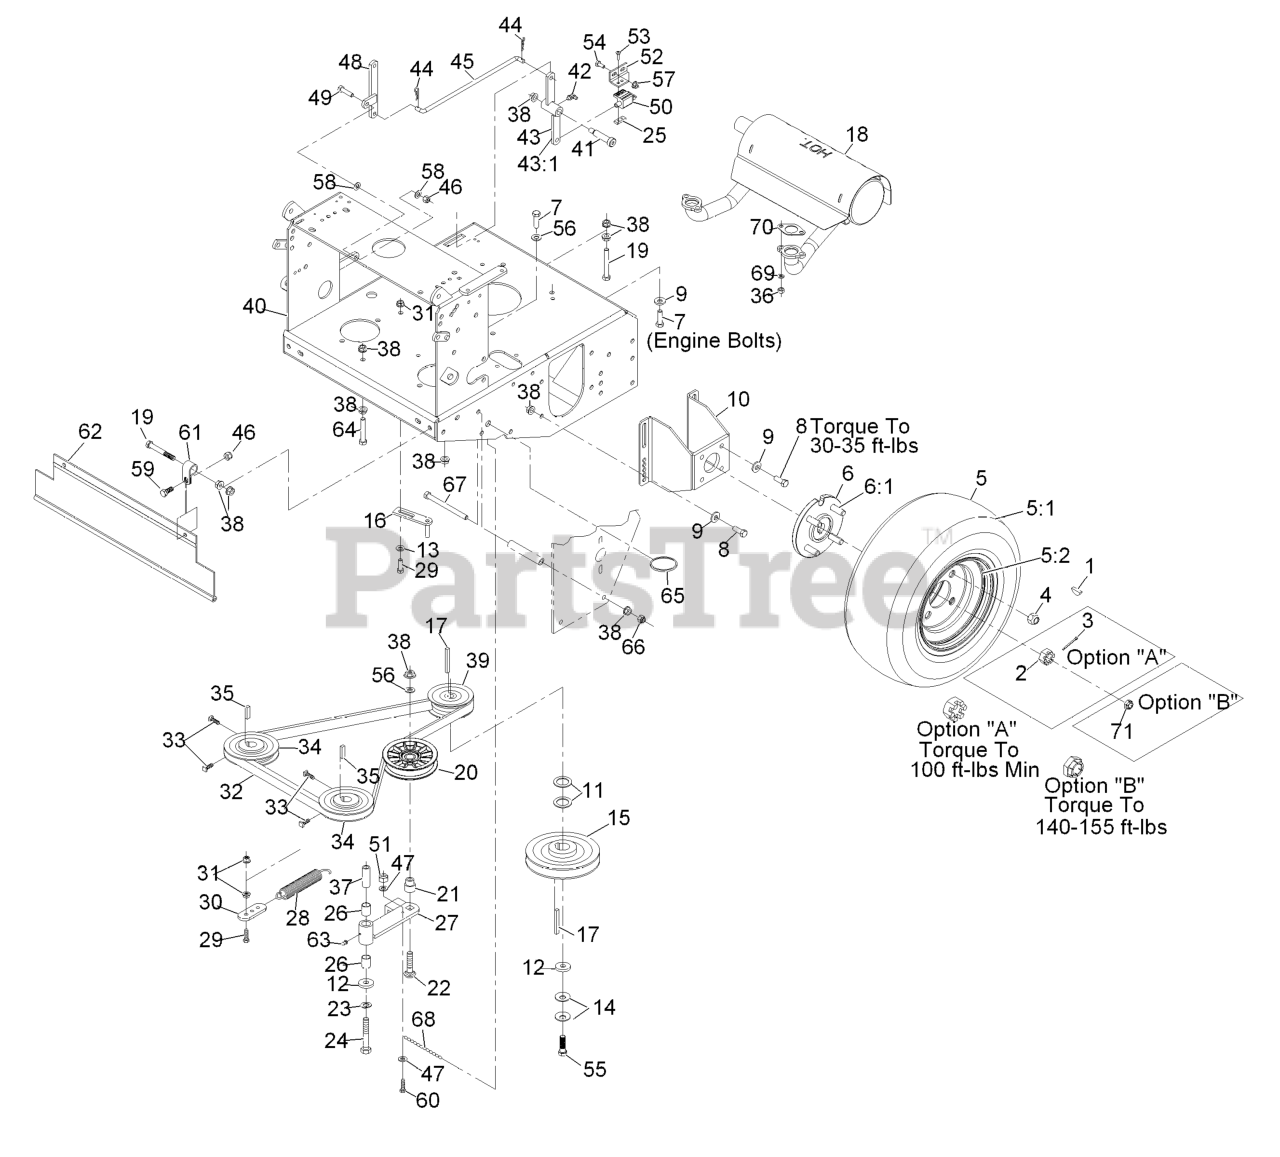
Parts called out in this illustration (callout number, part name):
1	KEY-WOODRUFF
2	NUT-HEX, SLOTTED
3	PIN-COTTER
4	NUT-LUG
5	WHEEL AND TIRE ASM
5:1	TIRE-TURFMASTER
5:2	RIM-WHEEL
6	WHEEL HUB ASM
6:1	STUD-WHEEL
7	SCREW-HH
8	SCREW-HH
9	WASHER-BELLEVILLE
10	MOUNT-MOTOR
11	WASHER-SPACER
13	WASHER-SPRING
14	WASHER-SPRING
16	GUIDE-BELT
18	MUFFLER,HORIZONTAL
19	SCREW-HH
20	PULLEY-IDLER, FLAT
21	BUSHING-IDLER
22	SCREW-CARR
23	WASHER-LOCK
24	BOLT-CARR
25	PLATE-TAPPED
26	SLEEVE-BEARING
27	IDLER ARM ASM
28	SPRING-EXTENSION
29	SCREW-HH
30	ANCHOR-SPRING
32	BELT-COG
33	SCREW-SET
34	SHEAVE ASM
37	BUSHING
38	NUT-HHF, WHIZ
39	PULLEY
40	DECK,ENGINE W/DECALS
42	FITTING-GREASE, 90 DEG
43	BELLCRANK ASM
44	PIN-COTTER
45	LINKAGE-ENGAGE, BLADE
46	NUT-LOCK, NI
47	WASHER-FLAT
49	SCREW-HH
50	SWITCH-OPEN, NORMALLY
51	NUT-LOCK, NI
52	BRACKET-SWITCH, BLADE
53	SCREW-PPH
54	SCREW-HH
55	SCREW-HH
56	WASHER-FLAT
58	WASHER-PLAIN
59	SCREW-HH
60	SCREW-HSH
61	CLIP-LOOM
62	SHIELD-DRAG
63	FITTING-GREASE
64	SCREW-HH
65	RING-SPLIT
66	NUT-LOCK, NI
67	SCREW-HH
68	CHAIN-LINK, TWIST
69	WASHER-LOCK
70	GASKET-EXHAUST
71	NUT-LOCK
